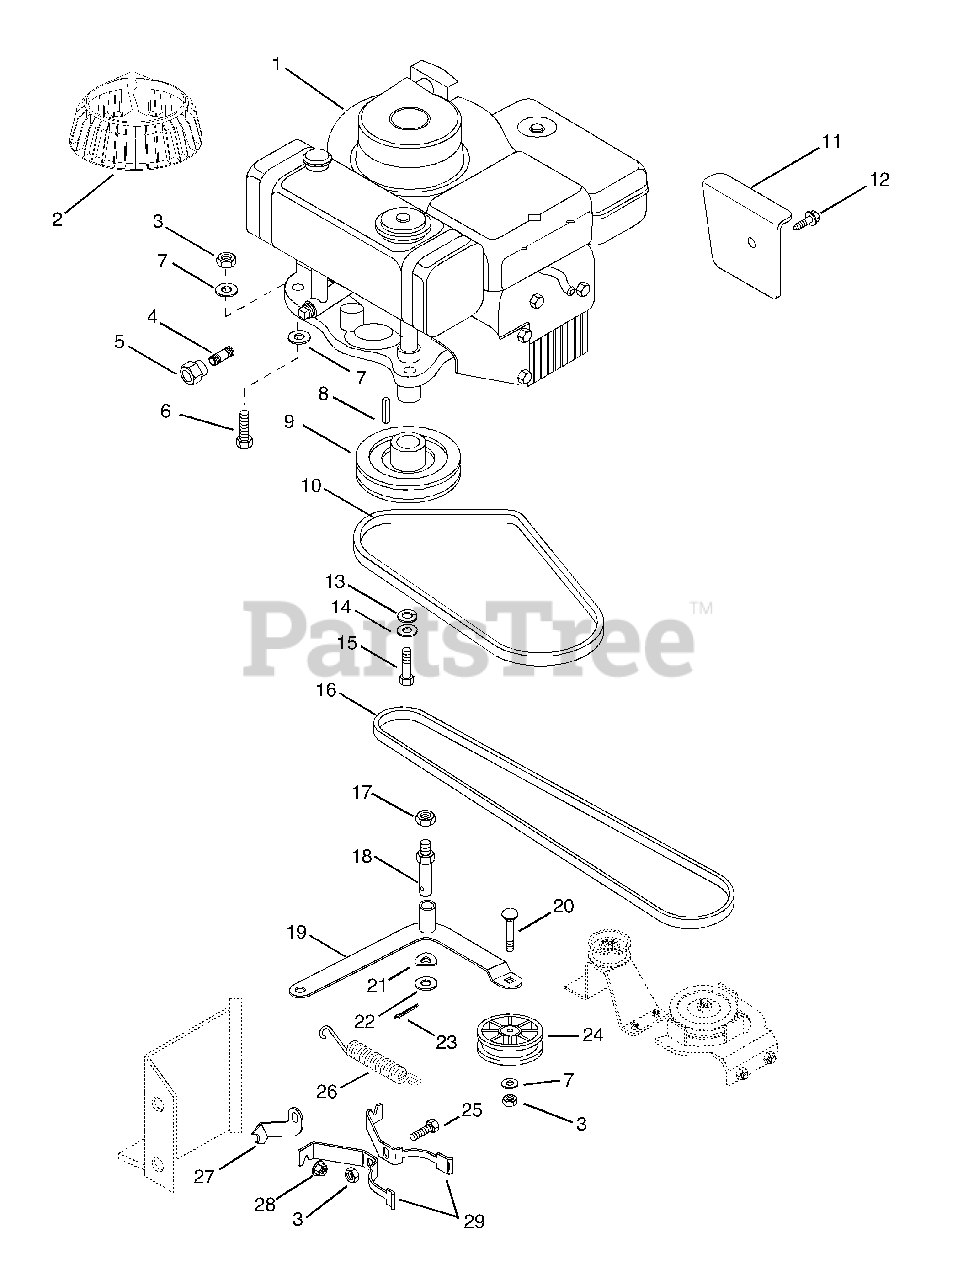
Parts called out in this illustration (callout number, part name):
1	ENGINE BRIGGS 9.0HP I/C
2	PRE-GUARD- REWIND (B&S#280685)
3	@NUT-LK-CTR .31-18 YWZC
5	PIPE CAP
6	@BLT-HEX .31-18X1.50 GR5 YWZC
7	WSHR-FL-STL .328X.875X.062YWZC
8	KEY-STR .25X2.0X.25
9	ENGINE SHEAVE
10	V-BELT, 3L-RAW EDGE
11	GUARD
12	@SCR-TAP 10-24X.375 HWH YZ TR
13	WSHR-FL-STL .505X1.140X.250
14	WSHR-LK .438X.133 HVY YWZC
15	BLT-HEX .44-20X1.25 GR5 YWZC
16	V-BELT, HA-RAW EDGE
17	@NUT-LK-CTR .38-16 YWZC
18	SHOULDER STUD
19	IDLER ARM
20	@BLT-RDHDSQNK .31-18X1.50 G5YZ
21	WAVE WASHER .531X.781X.125FH
22	WSHR-FL-STL .505X.875X.024 YWZ
23	@PIN-CTR .09X.75 EXTPRSQCT YWZ
24	IDLER-FLAT 2.75X.31 DAYCO
25	@BLT-HEX .31-18X.75 GR5 YWZC
26	SG-TENS .062X.72X6.65 WLD 7
27	BELT FINGER BRACE
28	@NUT-SPNLK-FLG .312-18 YWZC
29	BELT FINGER
